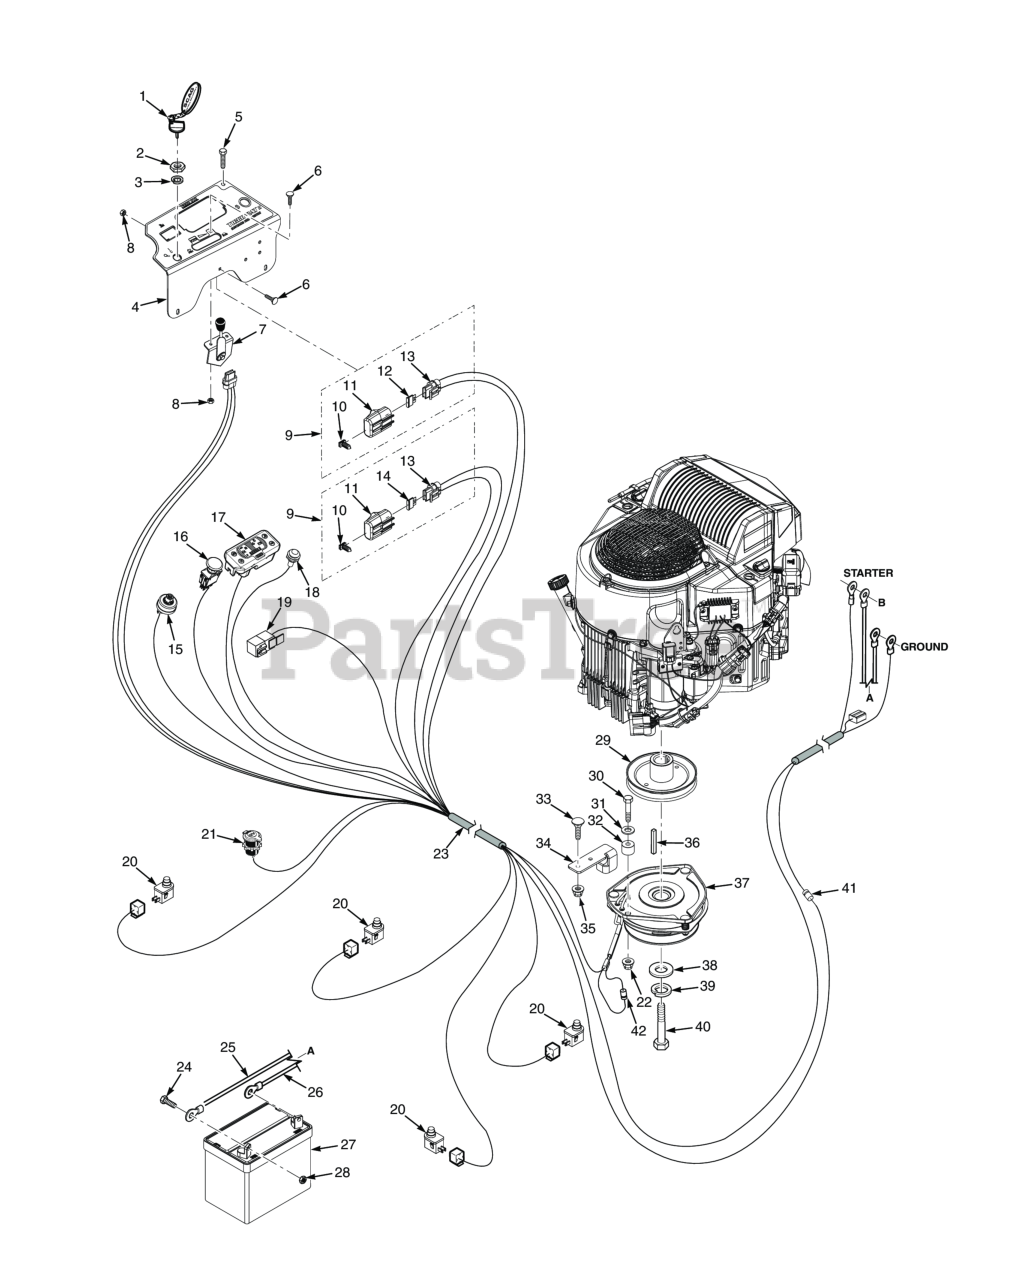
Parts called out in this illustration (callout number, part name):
1	Key, Assembly w/Fob
2	Nut, 5/8-32 Special
3	LOCK WASHER, 5/8" INTERNAL TOOTH
4	Instrument Panel w/Decal
5	CAP SCREW, 1/4-20 X 1/2" SERRATED FLANGE HEX
6	Bolt, Carriage #10-24 x 1/2"
7	Control, E-Gov Throttle
7	Knob, Throttle
8	Nut, Elastic Stop #10-24
9	Single Fuse Assy., Excluding Fuse
10	Clip, Fuse Holder
11	Cover, Sealed Single
12	Fuse, 5 Amp
13	Fuse Holder Assembly
14	FUSE, 20 AMP BLADE TYPE AUTOMOTIVE
15	KEY SWITCH(INCLUDES MOUNTING HARDWARE)
16	Switch, PTO - 10 Amp
17	Tiger Eye, Cluster Gauge
18	Indicator Light, Glow Plugs (Includes Mounting Hardware)
19	Relay, 12V 40 AMP Standard
20	Switch, Interlock, Normally Open
21	Power Plug, 12V
22	HEX NUT, ELASTIC STOP LOCK, 5/16-18
23	Wire Harness, STCII-26FT-EFI
24	Bolt, Hex Head 1/4-20 x .5" Battery, (Not Available Through Scag)
25	Battery Cable, 25" Red
26	Battery Cable, 27" Black (35BV & 37BV-EFI) - Briggs & Stratton
27	Battery, 350 CCA
28	Nut, 1/4 - 20 Hex
29	Pulley, 5.75" Dia. - 1.125 Bore
30	Bolt, Hex Head 5/16-18 x 2-1/2" (x3) (35BV & 37BV-EFI)
31	Flatwasher, 5/16-.375 x .875 x .083 (35BV & 37BV-EFI)
32	BUSHING, UHMW
33	Bolt, 5/16-18 x .75 RHSN Carriage
34	ANTI ROTATION
35	Nut, Flange Head Elastic Stop 5/16-18
36	Key, 1/4 x 1/4 x 3-1/2"
37	Clutch w/Tag GT3.5--FE05 (61)
38	Flatwasher, 7/16-.469 x 1.75 x .25 (48, 52)
39	Lockwasher, 7/16� Spring
40	Bolt, Hex Head 7/16-20 x 2-3/4" w/ Patch
41	Decal, Forward Speed Selector
42	Diode, 600V 6 Amp
